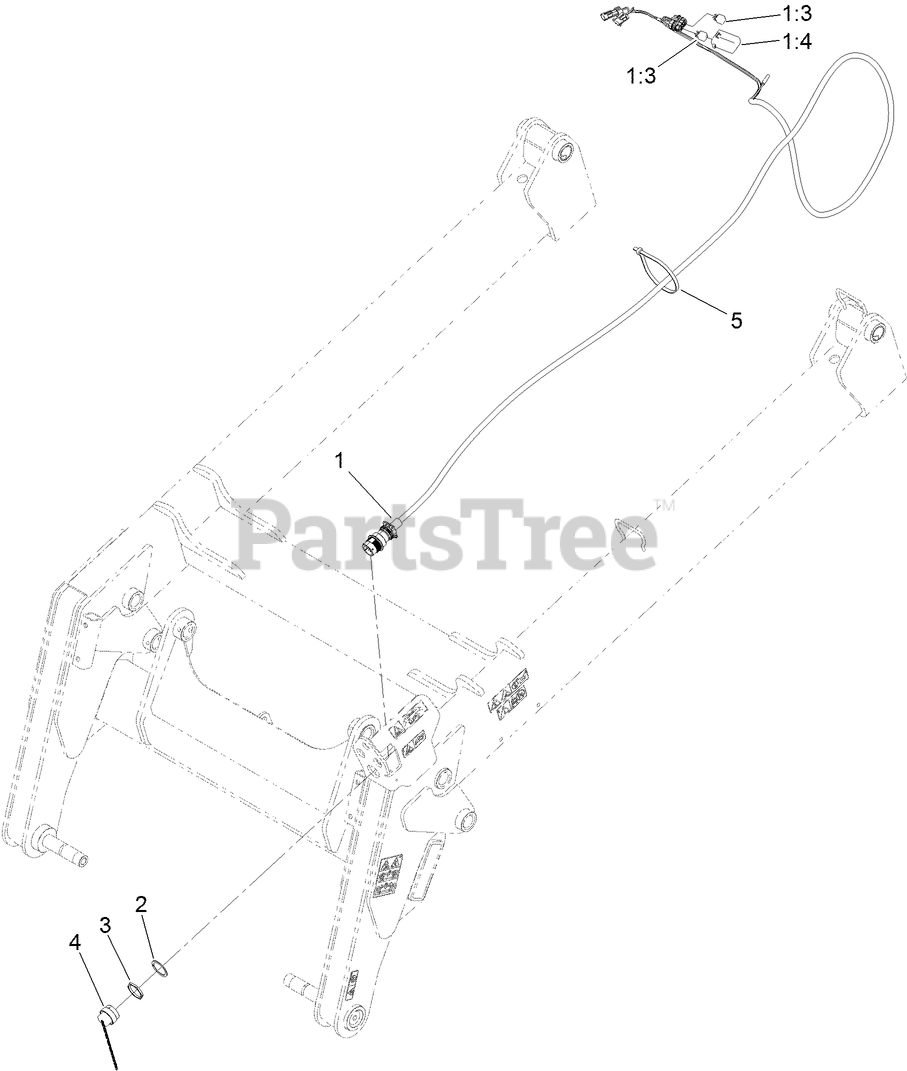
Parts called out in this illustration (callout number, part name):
1	HARNESS-WIRE, STANDARD BOOM
1:3	RELAY-MICRO
2	WASHER-LOCK
3	NUT-CONNECTOR
5	TIE-CABLE
